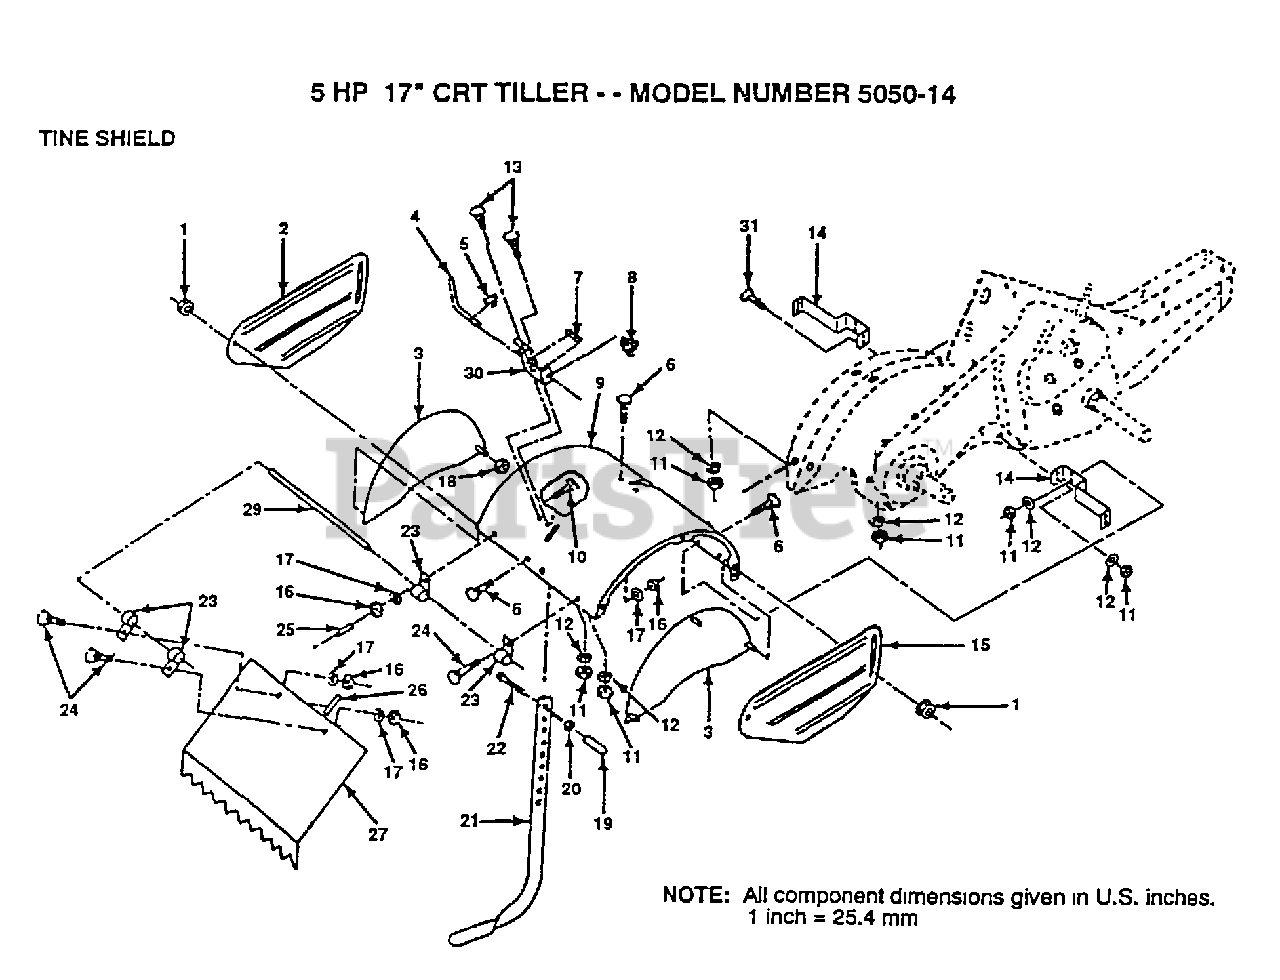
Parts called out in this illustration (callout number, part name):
1	NUT
2	SHIELD.SD.OUT.LH
4	STAKE PIN TI
5	KLIP RING TI
6	BOLT
7	SPRING TI
8	SPRING CRT
10	BOLT
11	NUT.HEX.5/16-18
12	LOCKWASHER
13	BOLT CRT
14	"BRACKET,SHIELD"
15	SHIELD.SD.OUT.RH
17	LOCKWASHER
18	LOCKNUT TI
19	GRIP CRT
20	NUT.HEX.3/8-16UNC
22	BOLT
23	HINGE CRT
24	BOLT
25	VINYL CAP TI
26	PAD IDLER TI
29	PIN HINGE
30	LATCH BRACKET TI
31	BOLT
